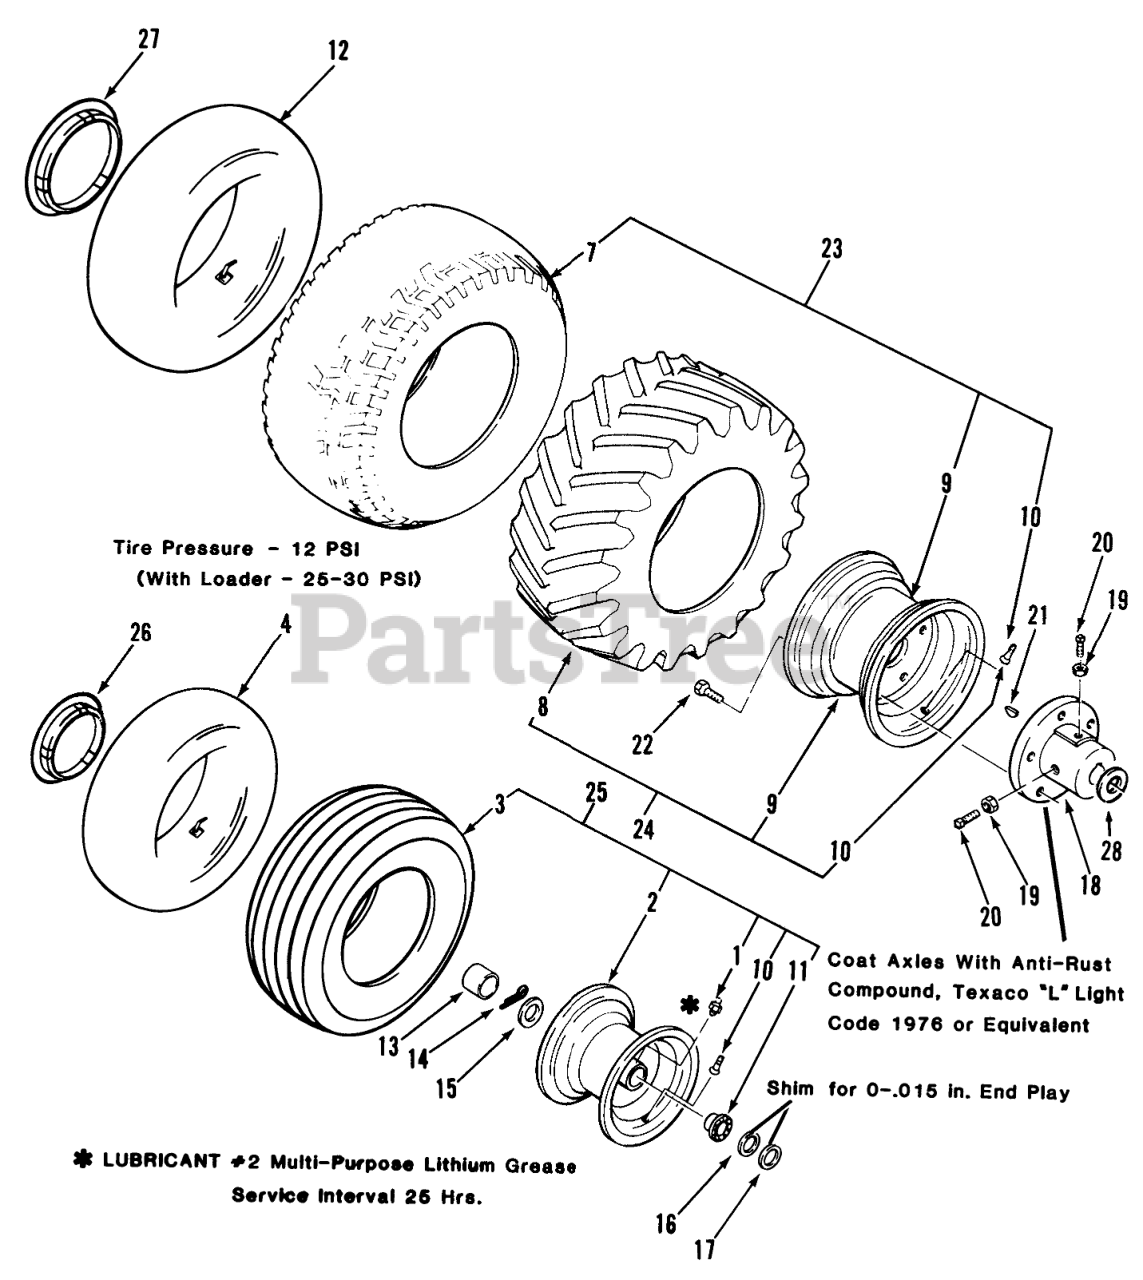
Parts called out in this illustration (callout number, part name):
1	ZERK-GREASE
3	TIRE-15 X 6.00-6
9	WHEEL
10	VALVE
11	BEARING-WHEEL
14	COTTER PIN-4
15	WASHER-WHEEL
16	WASHER
17	WASHER-SHIM
21	KEY-WOODRUFF
25	ASM-Wheel Tire
26	ORDER 107-9223(NO LOGO)HUBCAP
